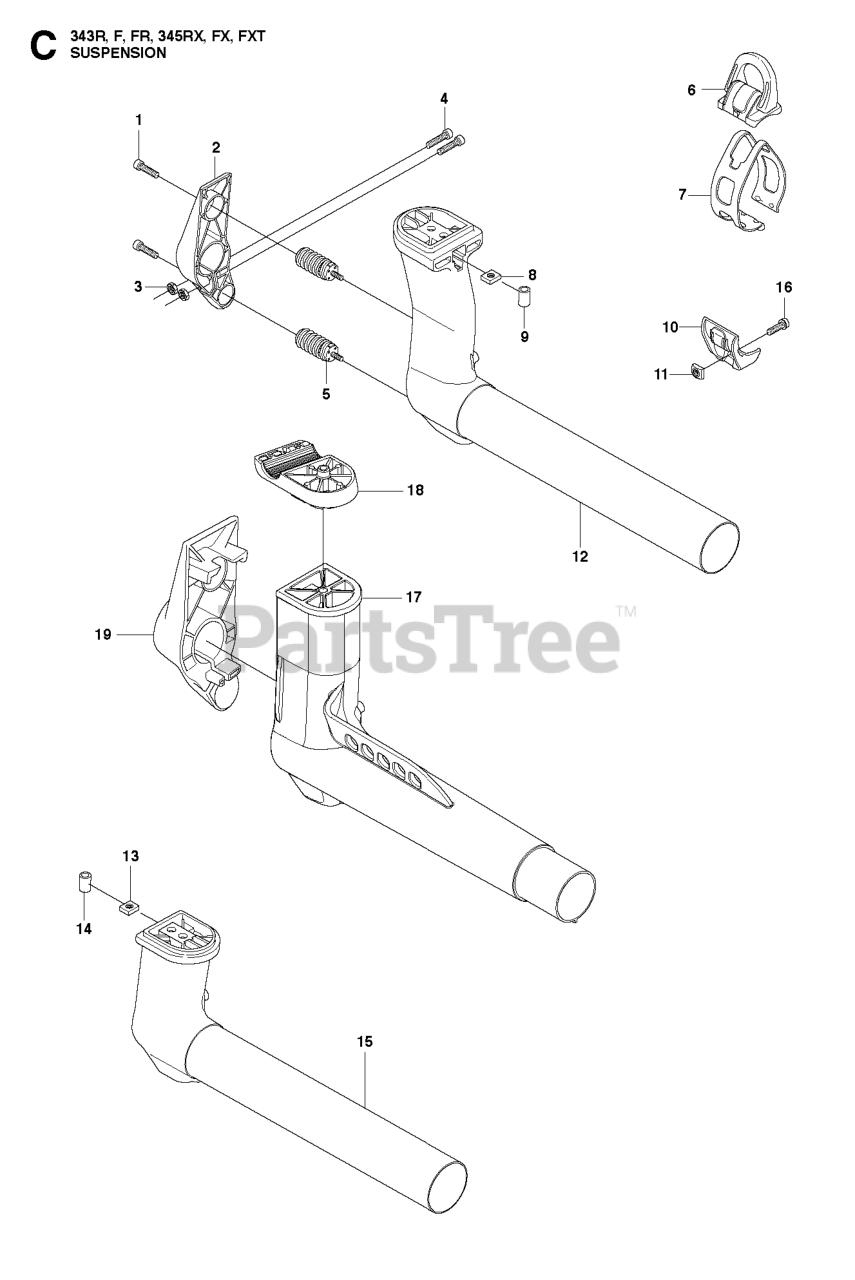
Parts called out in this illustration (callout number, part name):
2	HOLDER
6	LOOP
10	BRACKET, LOWER HANGER
11	SQUARE NUT M5
12	SUPPORT
15	SUPPORT
17	SUSPENSION
18	HANDLEBAR BRACKET
19	HOLDER ANTIVIBRATION
